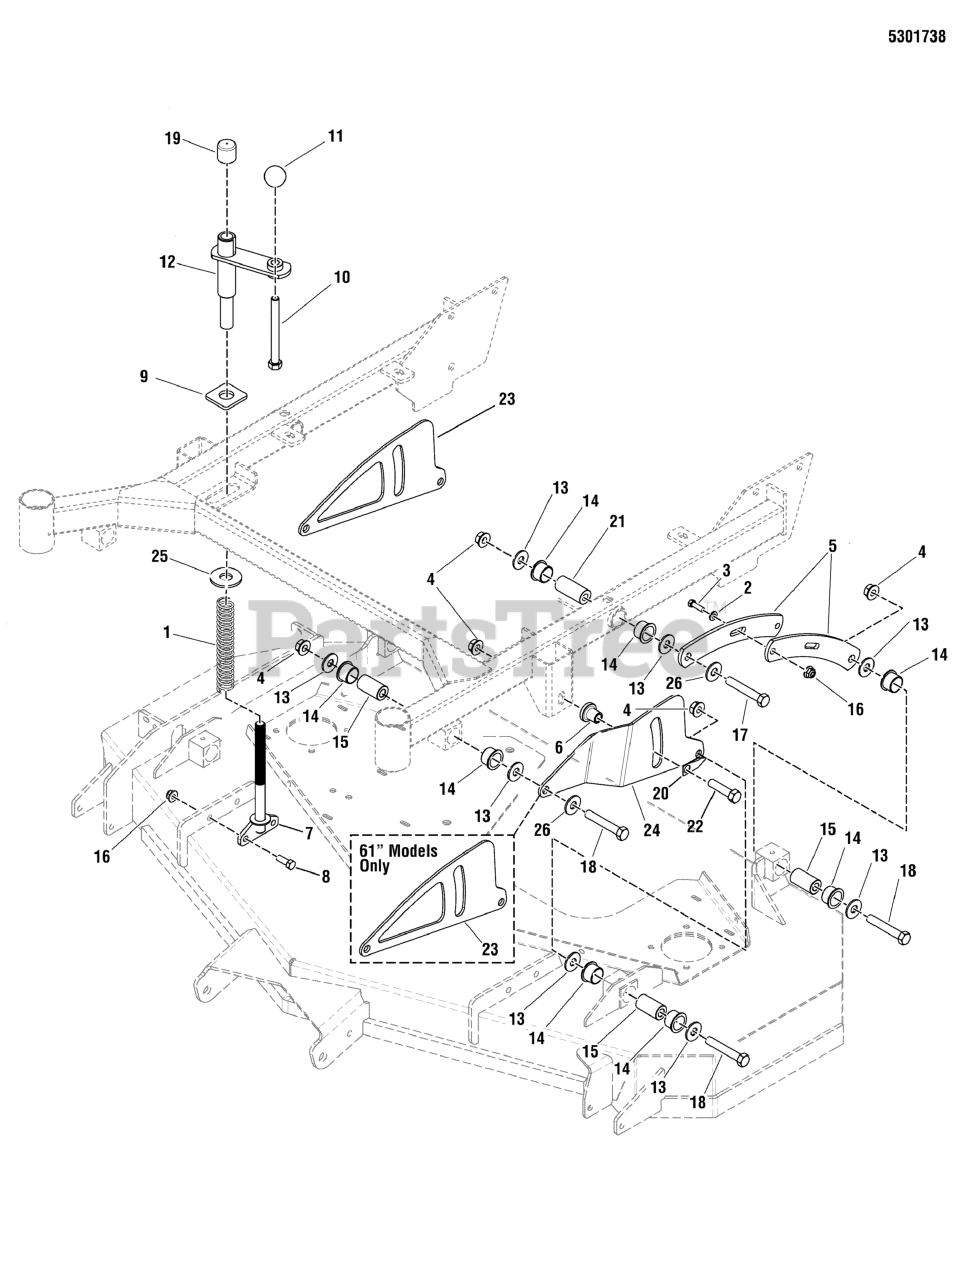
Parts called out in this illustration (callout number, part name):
1	SPRING, COMP, .840 X 1.044 X 6.7, BLK
2	WASHER, 3/8 GD.9 FLAT
3	BOLT, 3/8-16 X 1-1/4" GD5 CZ
4	NUT, Hex Flange, Nylock, 1/2-13
5	BAR, DECK LIFT - ADJ, SW20-52-61 - RED
6	SPACER, .515 X .75 X 1.06 SHLDR
7	ROD, DECK LIFT, SW30
8	BOLT, 3/8-16 X 1" GD5 CZ
9	WASHER, SQ, .810ID X 1.63SQ X .14TH, CZ
10	BOLT-1/2-13 X 5 GD5 YZ
11	KNOB, PLASTIC, 1/2-13
12	DECK CRANK, SW30 - BLK
13	WASHER, 1/2 USS
14	BUSHING, 1.00X1.13X.75, PLA
15	SPACER, .52 X 1.00 X 1.825
16	NUT, 3/8-16 HEX NYLOCK FLANGE
17	BOLT, 1/2-13 X 3-1/2, HEX HD, GD5, CZ (SV)
18	BOLT, 1/2-13 X 3" GD5 CZ
19	CAP, VINYL, 1.062 X 1.00 BLK
20	POINTER, DECK HEIGHT, SW30
21	SPACER, .50 X 1.00 X 2.25
22	BOLT, 1/2-13 X 2" GD5 CZ
23	PLATE, DECK HEIGHT INDICATOR, RH
24	PLATE, DECK LIFT, LH, SW30-52
25	WASHER, 3/4 USS
26	WASHER, 1/2 SAE
